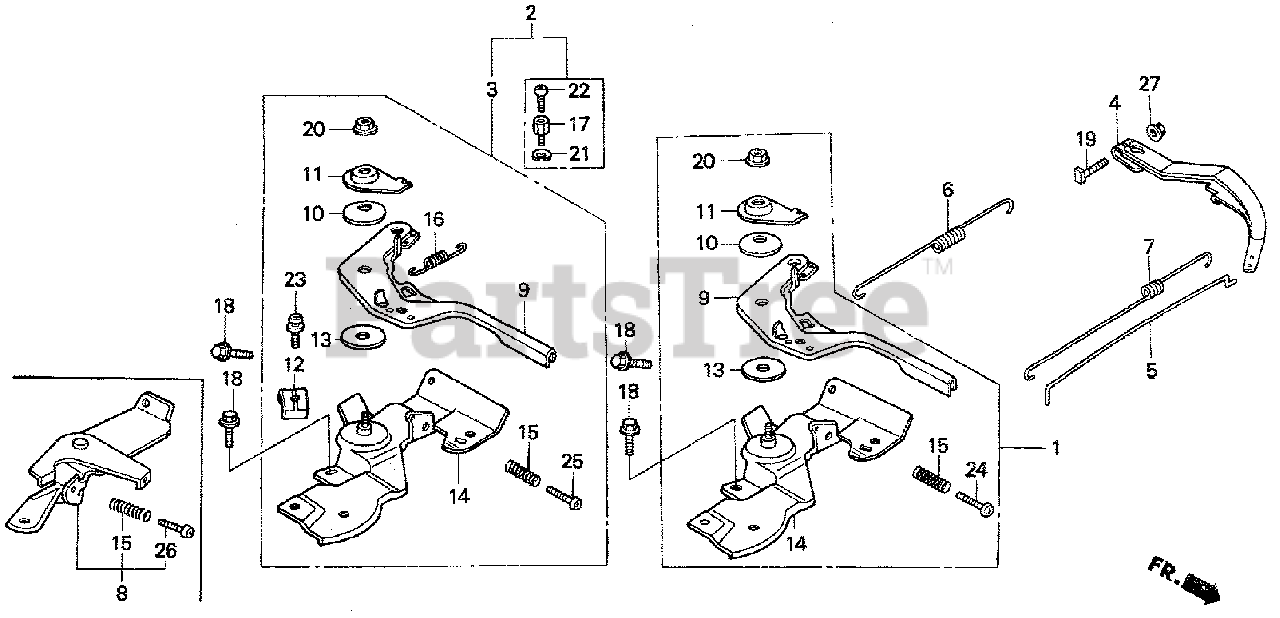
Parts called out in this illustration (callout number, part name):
3	CONTROL ASSY. (REMOTE)
4	ARM, GOVERNOR
5	ROD, GOVERNOR
6	SPRING, GOVERNOR
7	SPRING, THROTTLE RETURN
9	LEVER, CONTROL
10	SPRING, LEVER
11	WASHER, CONTROL LEVER
12	HOLDER, CABLE
13	SPACER, CONTROL LEVER
14	BASE, CONTROL
15	SPRING, CONTROL ADJUSTING
16	SPRING, CABLE RETURN
18	BOLT, FLANGE (6X12) (CT200)
19	BOLT, GOVERNOR ARM
20	NUT, SELF-LOCK (6MM)
23	SCREW, PAN (5X16)
25	SCREW, PAN (5X25)
27	NUT, FLANGE (6MM)
